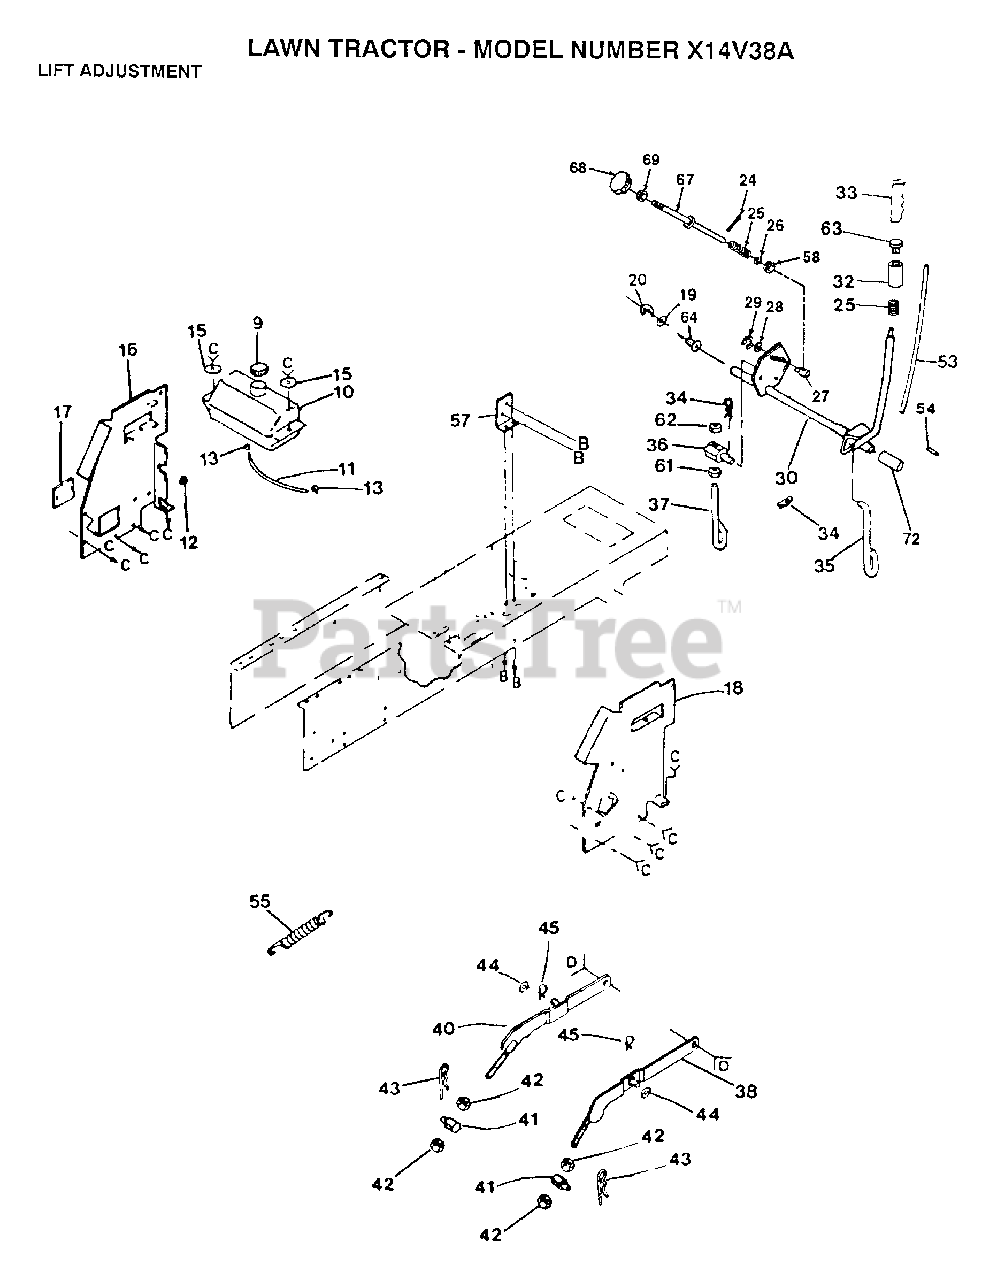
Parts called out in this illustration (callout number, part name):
10	TANK.FUEL.LT.
12	SNAP BUSHING T
13	HOSE CLAMP
15	WASHER
16	PANEL DASH LH
17	COVER ACCESS
19	WASHER
25	SPRING T
26	WASHER
27	TRUNION LT
28	WASHER
29	KLIP RING
33	GRIP
35	LIFT LINK LT
37	PIVOT PIN T
38	RH SUSP ARM ASM
40	LH SUSP ARM ASM
42	NUT
43	SPRING H
45	SPRING.RETAINER
54	PIN-GROOVE LT
57	BRACKET LT
58	NUT T
61	NUT
64	NYLON BEARING
67	LEVER ASSY LT
72	COUPLE LEVER T
